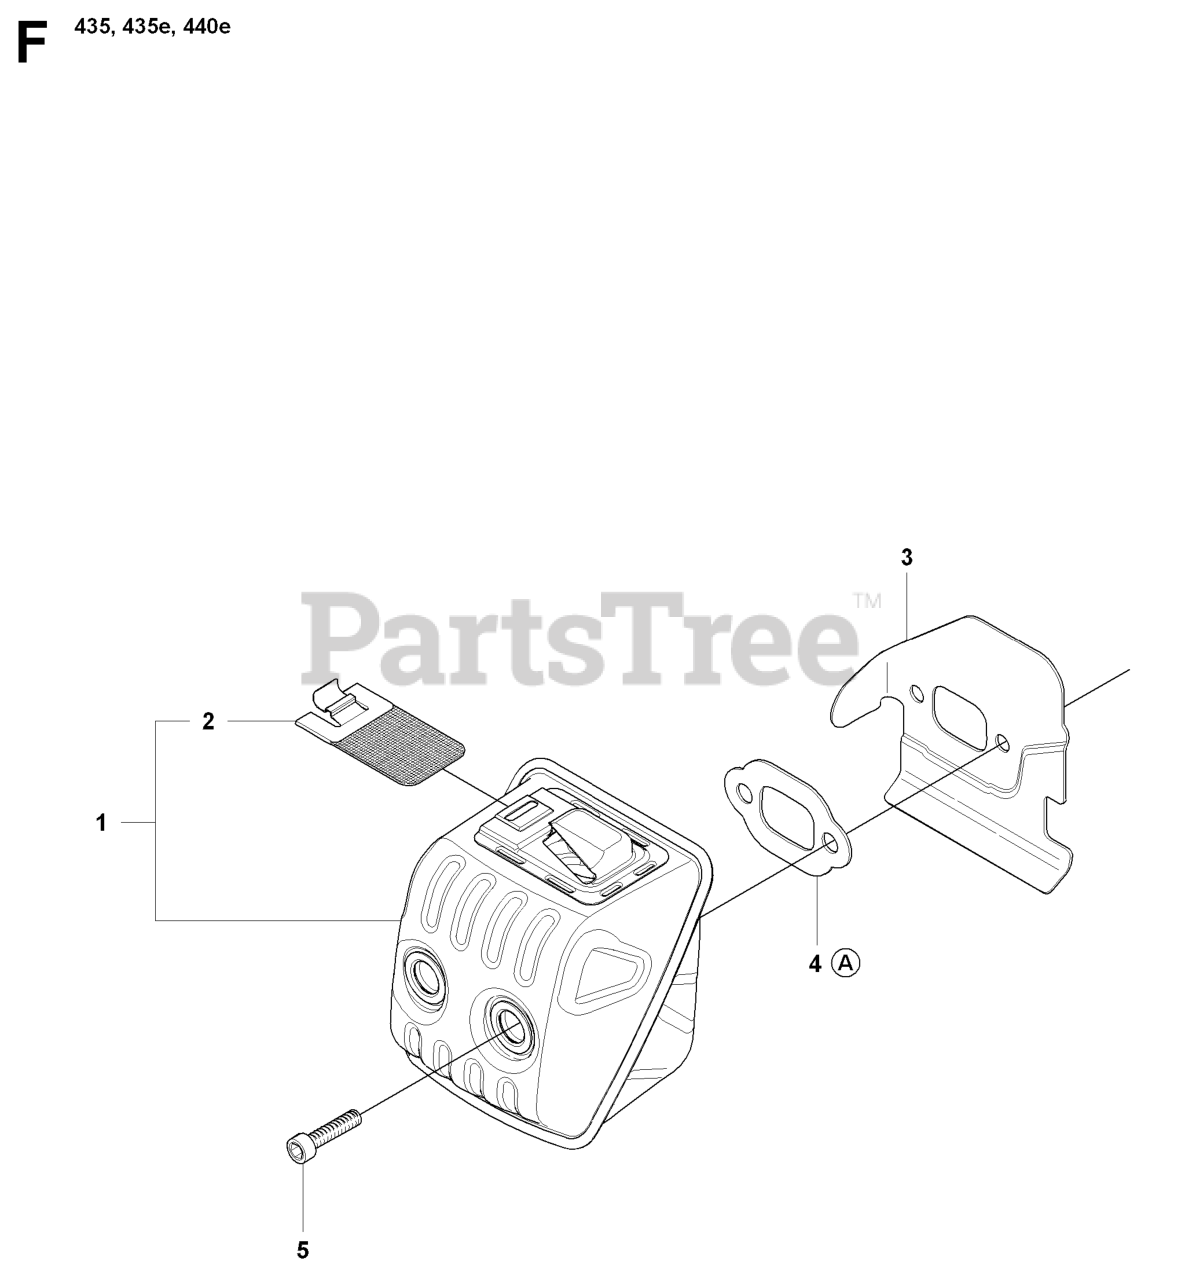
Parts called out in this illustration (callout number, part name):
1	%MUFFLER ASSY
2	SPARK ARRESTER
3	HEAT DEFLECTOR
4	RP GASKET
5	SCREW MC6S 6X16
